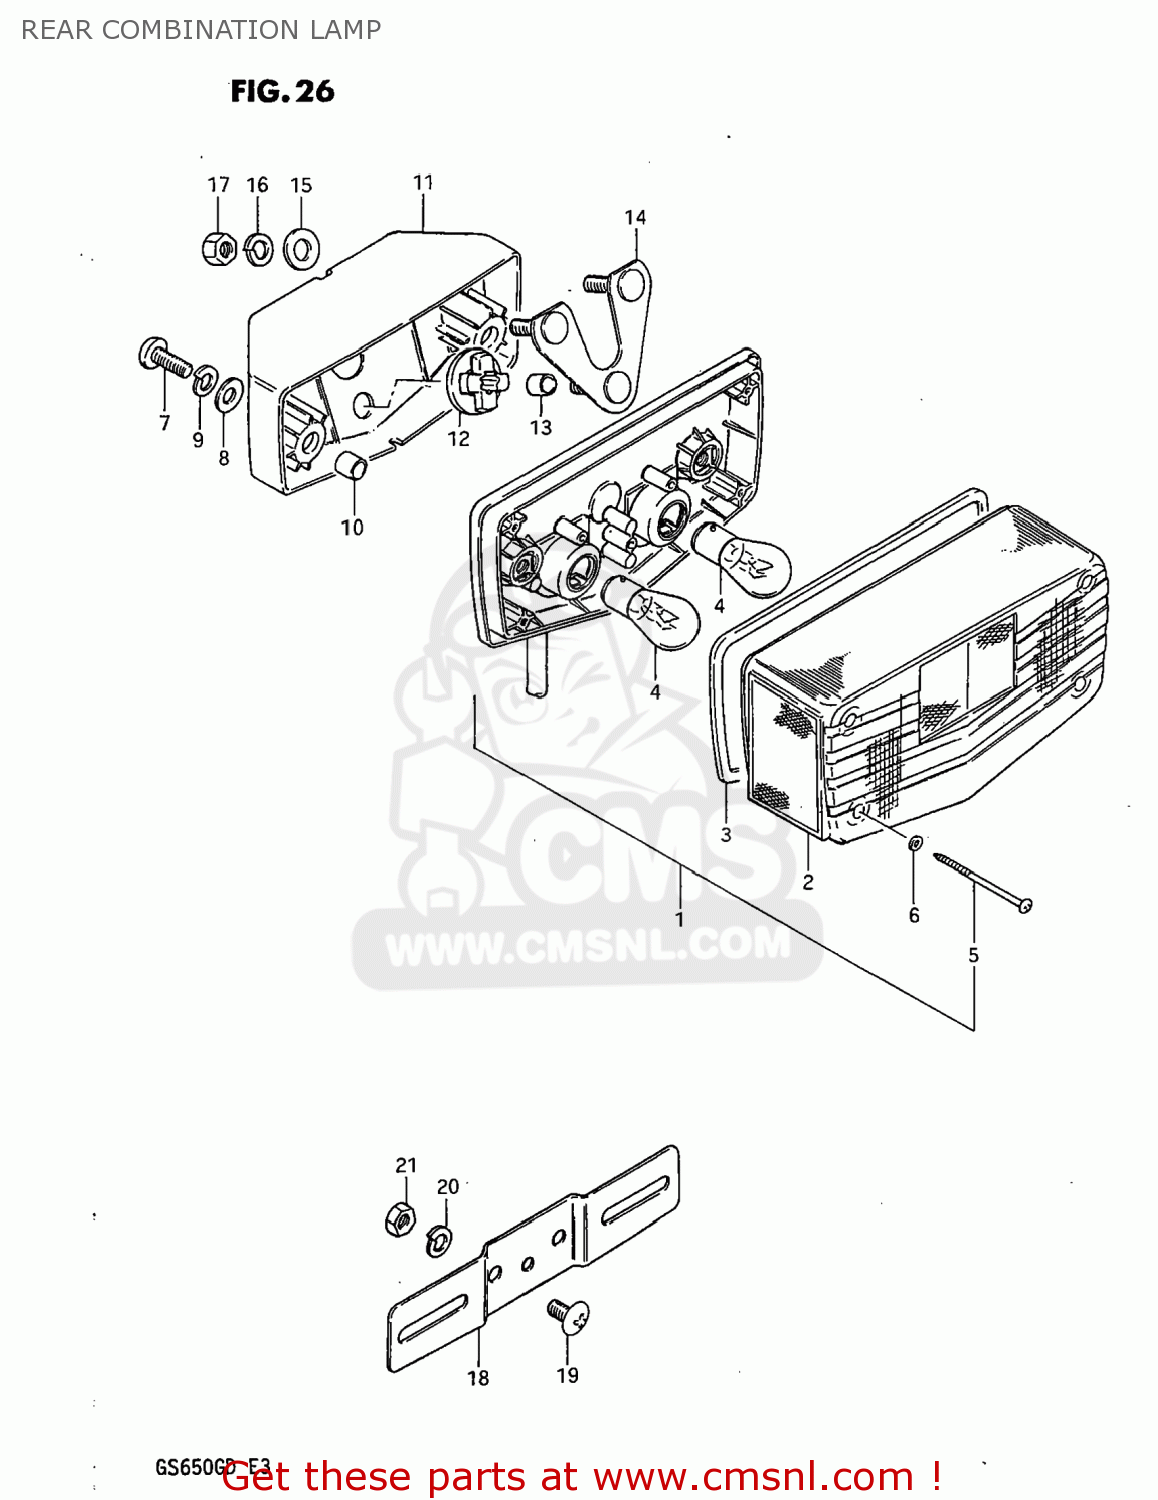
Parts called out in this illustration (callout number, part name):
1	LAMP UNIT,REAR COMBINATION
2	LENS,REAR COMBINATION LAMP
3	GASKET,REAR COMBINATION LAMP LENS (NAS)
4	BULB(12V23W)
5	SCREW
6	GASKET (NAS)
7	SCREW
8	WASHER
9	LOCK WASHER
10	SPACER,REAR COMBINATION LAMP
11	BRACKET UNIT,TAIL LAMP
12	CUSHION,REAR COMBINATION LAMP
13	SPACER,REAR COMBINATION LAMP
14	PLATE,REAR COMBINATION LAMP
15	WASHER
16	LOCK WASHER
17	NUT
18	PLATE,REAR LICENSE
19	SCREW
20	LOCK WASHER
21	NUT
